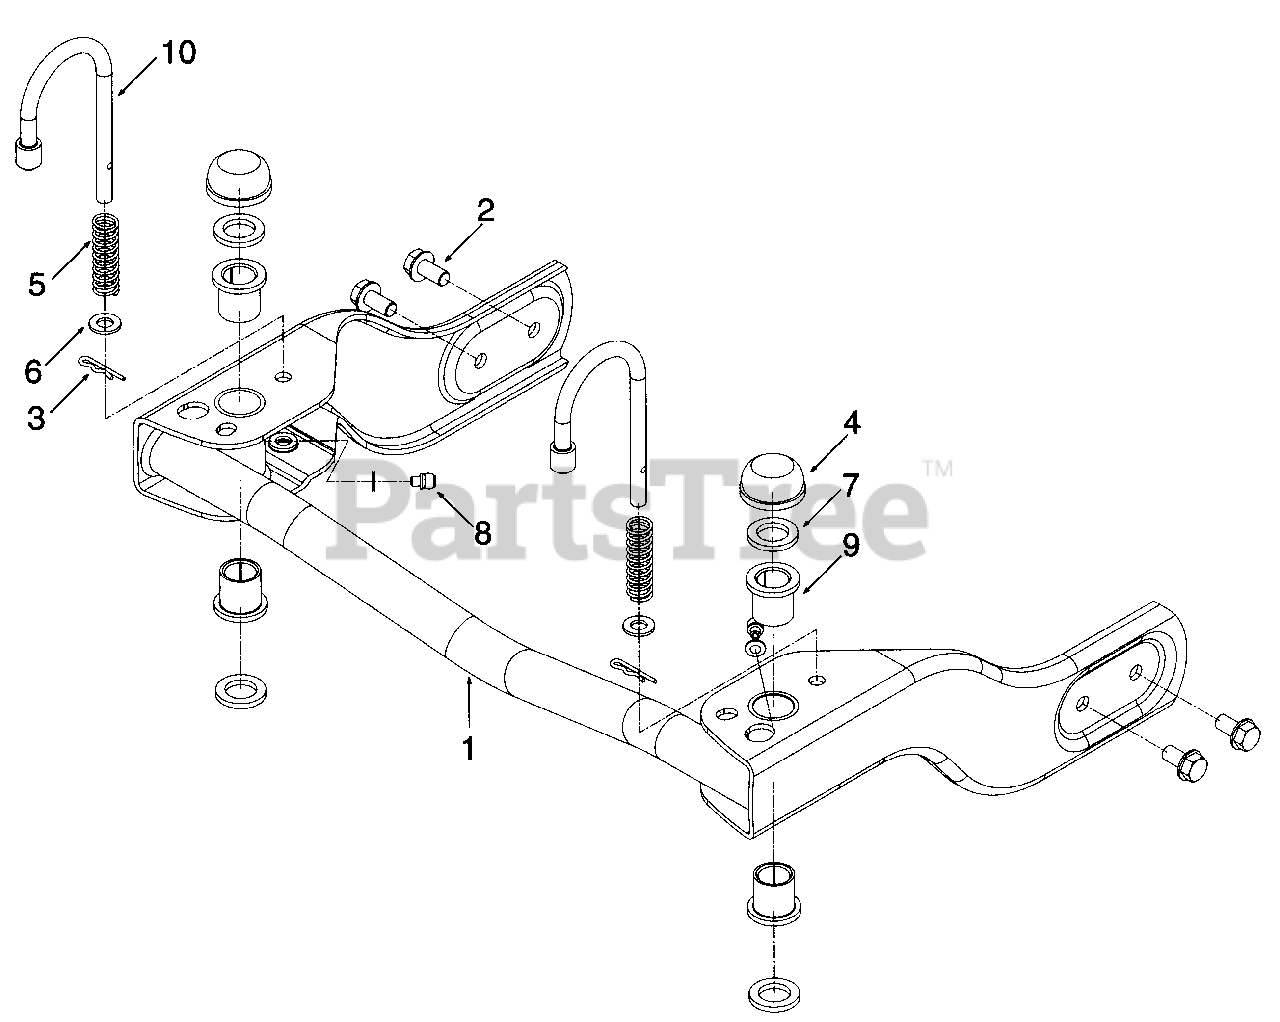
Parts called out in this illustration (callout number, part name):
2	HEX WASH HD TT -TAP SCR. 5/16-18 x .62 LG.
3	INTERNAL COTTER PIN .072 x 1.75 LG.
4	PUSH CAP 5/8
5	COMPRESSION SPRING .406 x .531 x 1.75 LG.
6	FLAT WASHER .330 ID x .630 x .06
7	FLAT WASHER 5/8 ID 1.00 OD
8	FITTING 3/16
9	FLANGE BEARING .632 ID
10	LOCK PIN/FRONT WHEEL
